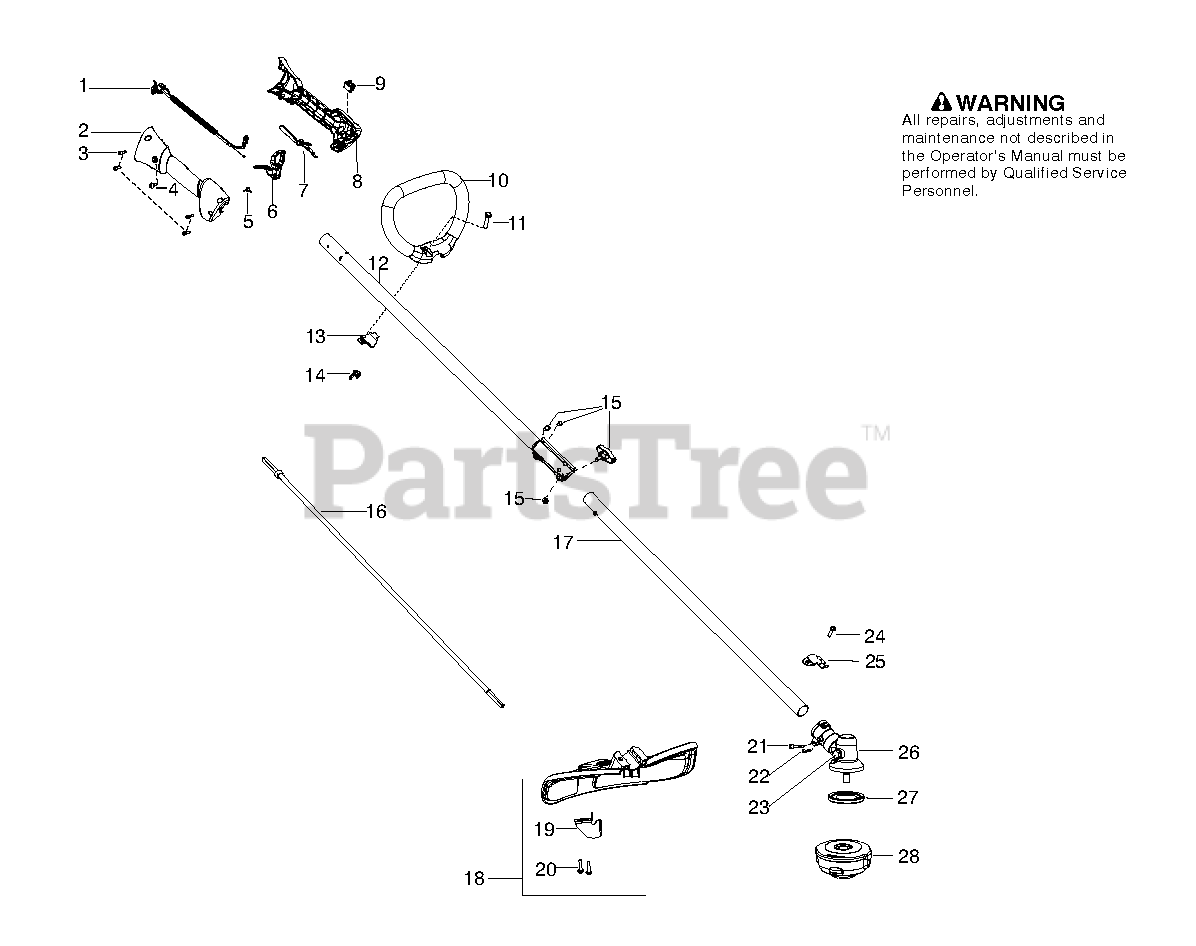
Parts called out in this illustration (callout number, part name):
1	ASSY CABLE / WIRE HARNESS
2	HSG THROTTLE RIGHT HVA
3	SCREW M4 X 1.75 PT 16MM
4	SCREW-10-14 X 1/2 PLASTITE
5	SPRING TRIGGER
6	TRIGGER THROTTLE HVA ORANGE
7	THROTTLE LOCKOUT HVA ORANGE
8	HSG THROTTLE LEFT HVA
9	SWITCH
11	BOLT, TYPE 2
12	KIT UPPER SHAFT SILVER
13	CLAMP ASSIST HANDLE
14	WINGNUT, TYPE 2
15	ASSY COUPLER BLACK
17	KIT LOWER SHAFT
18	KIT COBI SHIELD
19	Limiter - Line
21	SCREW - CARB. ADAPTOR
23	PLUG GREASE 9MM
24	SCREW 1/4-20 X 7/8 (TAP
25	BRACKET SHIELD STRAIGHT SHAFT
26	ASSY GEARBOX
27	DRIVE DISC
28	T25 TRIM HEAD 10MM LH
